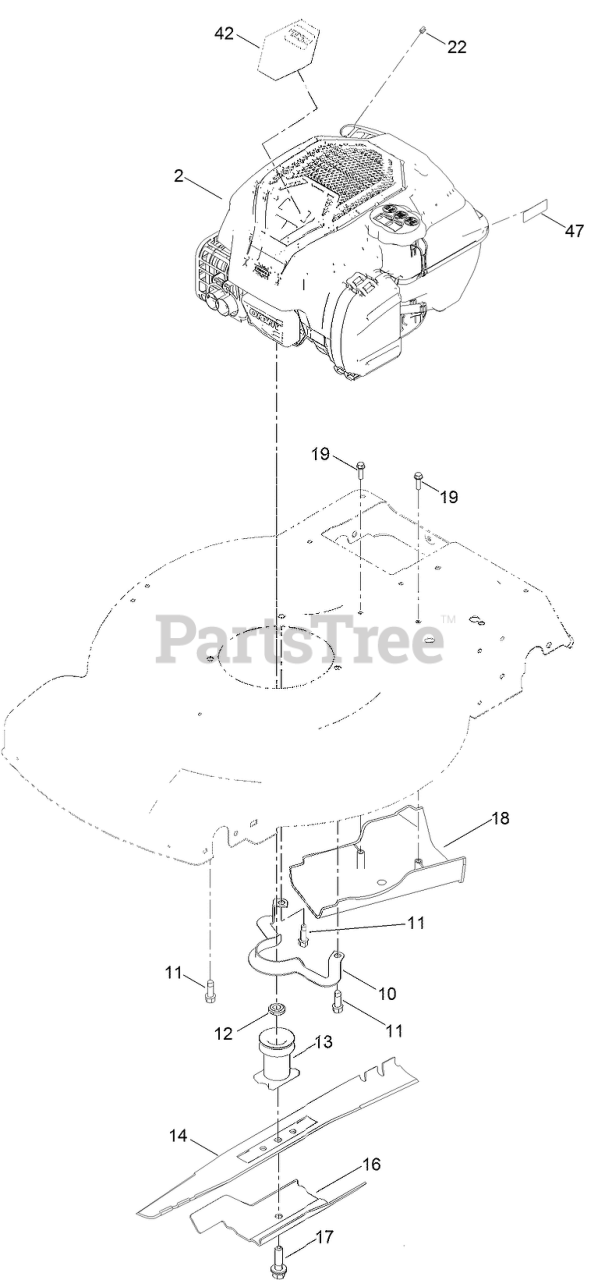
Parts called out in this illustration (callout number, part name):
10	GUIDE-BELT
11	SCREW-TAPTITE
12	SPACER-DRIVER
13	DRIVER-BLADE
16	ACCELERATOR-BLADE
17	BOLT-BLADE
18	COVER-BELT
19	SCREW-PLASTITE, HWH
22	STOP-ROPE
42	DECAL-SHROUD
47	DECAL-LEVEL, FUEL
